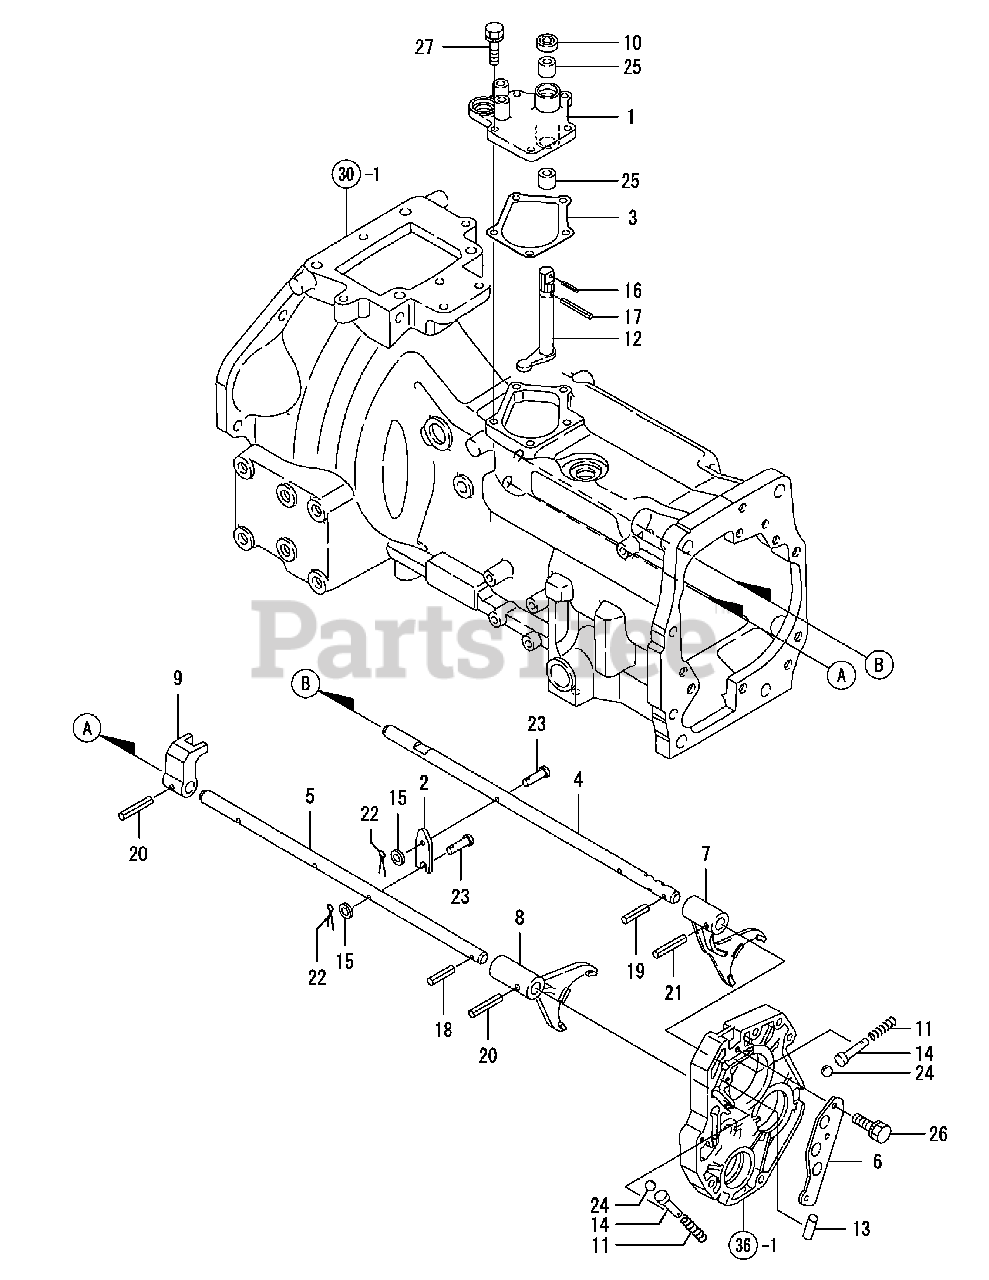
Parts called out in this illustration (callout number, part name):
1	RETAINER, LEVER
2	ARM, NEUTRAL START
3	GASKET, RETAINER
4	SHAFT 2-3,FORK
6	HOLDER,INTER LOCK
10	SEAL KBY 172406
12	ARM,GEAR SHIFT
14	PIN 4X35,FLAT HEAD.
15	WASHER 6.4*12.5*1
16	SPRING PIN 2X 12
17	SPRING PIN 4X32
18	SPRING PIN 6X25
19	SPRING PIN 6X25
20	SPRING PIN 6X32
21	SPRING PIN 6X32
22	COTTER PIN 1.6X18
24	BALL 5/16, STEEL
26	BOLT W/WASHER M8X20
